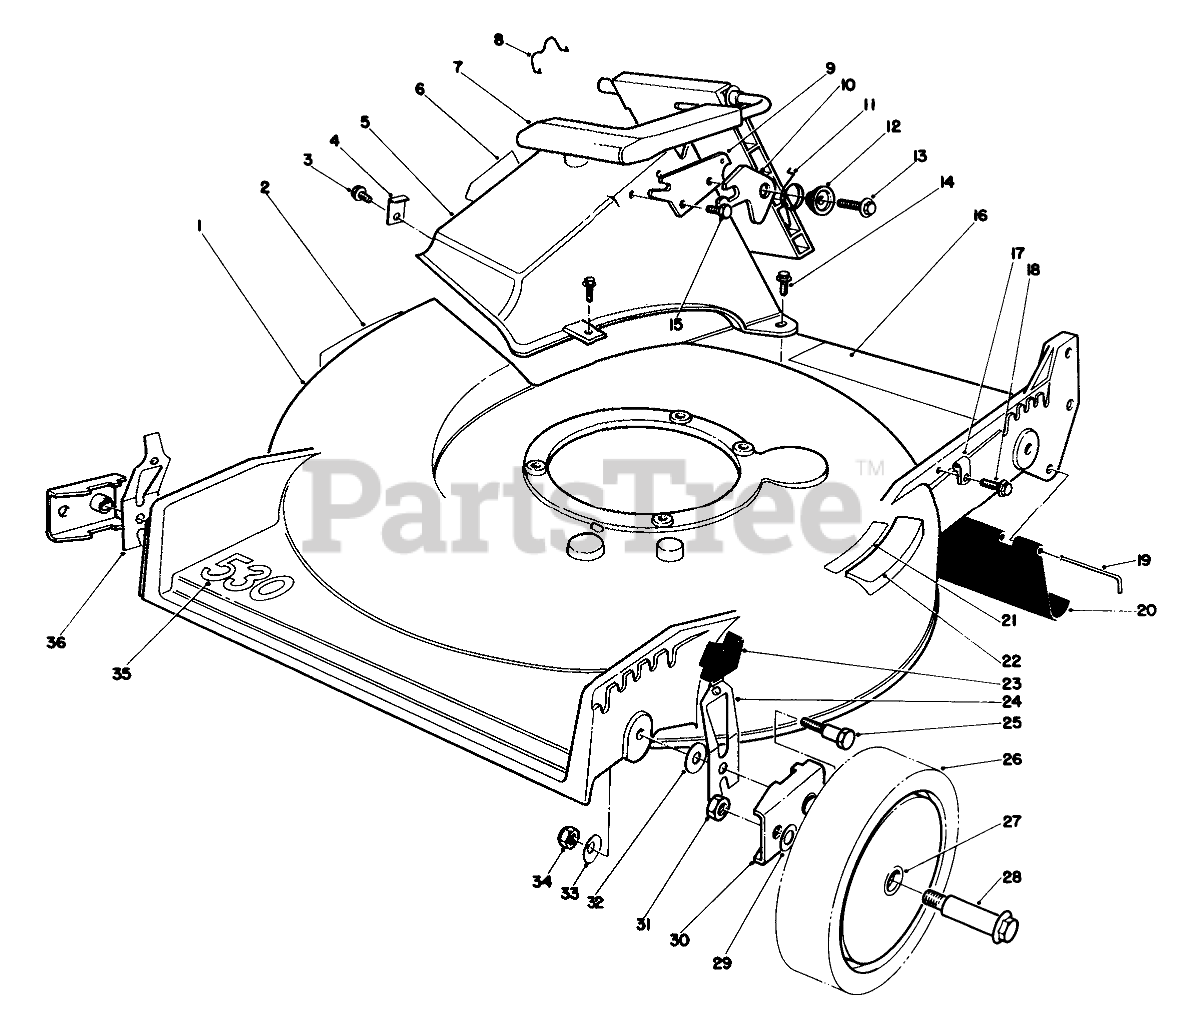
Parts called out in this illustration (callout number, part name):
1	Housing (Incl. Ref. #2)
2	DECAL-DANGER
3	SCREW
4	TUNNEL CLIP
5	Tunnel Discharge
6	Decal-Attention
7	Discharge Door Assembly
8	DOOR RET SPRING
9	DOOR LATCH PLATE
10	SAFETY LATCH
11	TORSION SPRING
12	DOOR SPACER
13	SCREW-HWH
14	SCREW-HWH
15	SCREW-PLASTITE
16	Danger-Decal
17	CLAMP-CABLE
18	SCREW
19	ROD-SHIELD
20	SHIELD-TRAILING
21	Decal-Place Foot Here
22	STEP PAD DECAL
23	KNOB-ARM
24	L. HP SPRING ARM ASM
25	PIVOT SCREW
26	Wheel & Tire Assembly (Inc. Ref. #27)
27	BUSHING
28	BOLT-WHEEL
29	WASHER
30	HP PIVOT ARM ASM
31	Nut
32	WASHER-PIVOT
33	WASHER-BELLEVILLE
34	NUT-LOCK, NI
35	Decal-530
36	R HP SPRING ARM ASM
